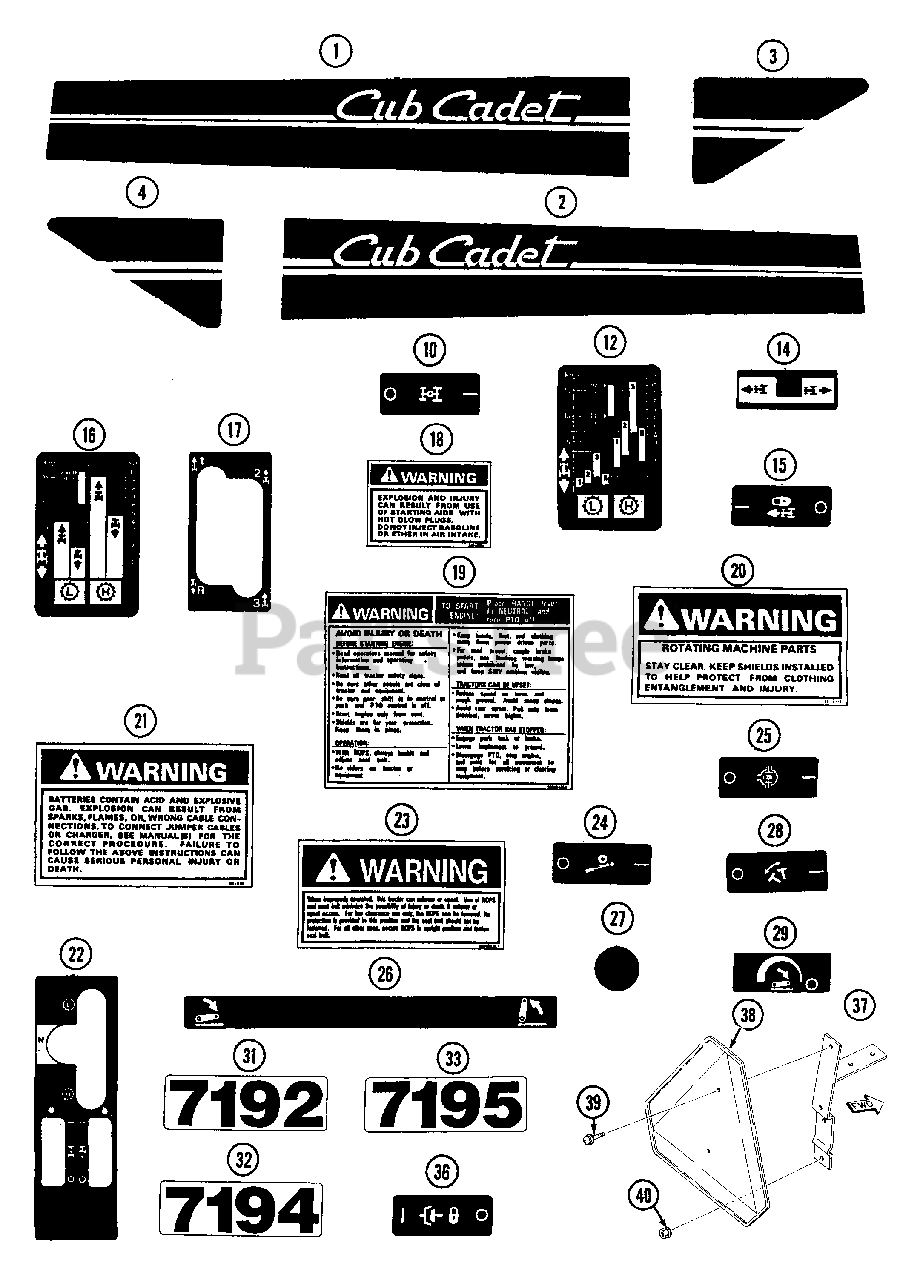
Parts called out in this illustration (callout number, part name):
1	Label, L Panel
2	Label, R Panel
3	Label, Rear L.H.
4	Label, Rear R.H.
10	Label, Rear L.H.
12	Label, Speed G
14	Label, HST Control
15	Label, SP Control
16	Label, Speed H
18	Label, Warning
19	Label, Warning
20	Label, Warning
21	Label, Warning
23	Label, Warning
25	Label, Diff. Lock
26	Label, Position
27	Label, Steering
31	Label, Model 7192
32	Label, Model 7194
33	Label, Model 7195
36	Label, Declutch
38	Emblem, SMV
